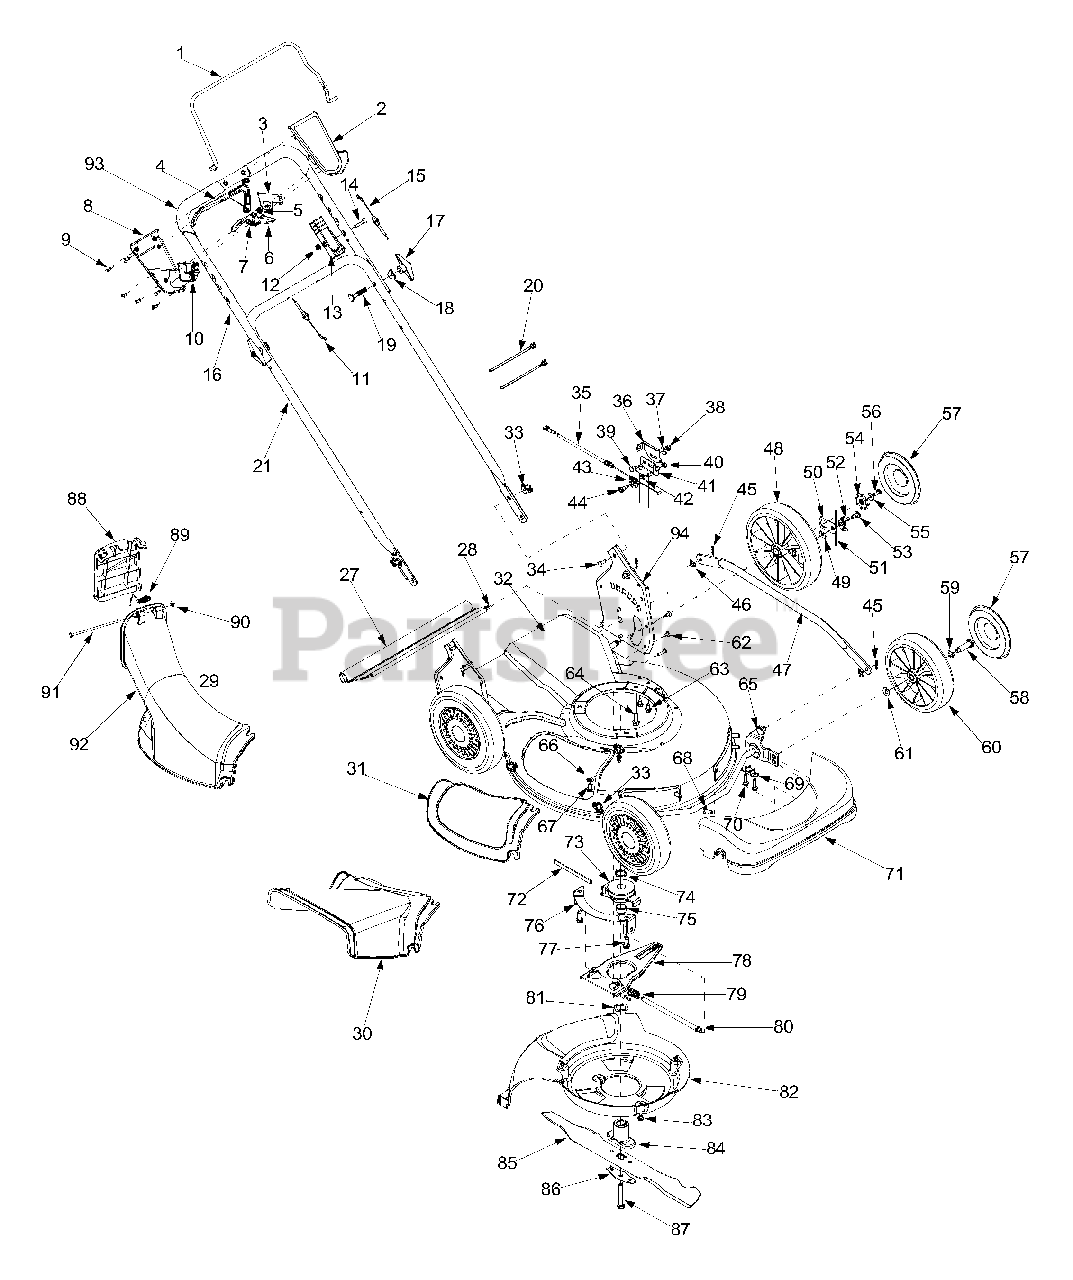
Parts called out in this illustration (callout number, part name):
1	Control Handle
2	Control Housing Kit
3	6 Spd. Rack Cable Bracket
4	Control Lever
5	Gear Insert
6	Shift Lever Spring
7	6 Speed Shift Lever
8	Control Housing Kit
9	C Sunk Tap Screw #10 x .75 Lg
10	Control Housing Kit
11	Drive Cable 51.0
12	Top Lock Nut 1/4-20
13	Control Housing
14	Oval C-Sunk Screw
15	Control Cable 46"
16	Upper Handle
17	Wing Nut
18	Saddle Washer .320 ID x .830 OD
19	Carriage Bolt 5/16-18 x 2.0
20	Cable Tie
27	Trail Shield
28	Trail Shield Wire
29	Chute Assembly
30	Side Discharge Chute
31	Mulch Cover
34	Carriage Bolt 1/4-20 x .75
35	6 Speed Cable
36	Cable Adjustment Bracket
37	Bell Washer .265 ID x .75 OD
38	Hex Nut 1/4-20
39	Carriage Screw 1/4-20 x .50
40	Hex Nut 1/4-28
41	Cable Mounting Bracket
42	Lock Washer 1/4
43	Roller Cable
44	Shoulder Screw .375 ID x 1/4-14
45	Cotter Pin
46	Bowed Washer
47	Single Lever Control Arm
48	Wheel 9 x 2
49	Top Lock Tab Weld Nut 1/4-20
50	Ratchet Pawl Plate
51	Plastic Spring Ratchet
53	Shld Screw .340 ID x .285 OD
54	Wheel Rachet
55	Bell Washer .265 ID x .75 OD
56	Hex Cap Screw 1/4-20 x .620
57	Hubcap
58	Shoulder Screw .498 x 1.445
59	Wave Washer .510 ID x .750 OD
60	Wheel 8 x 2
61	Spring Washer .401 ID x .870 OD
62	Screw 1/4-14 x .500
63	Screw 1/4-14 x .625
64	Hex Washer Screw 3/8-16 x 1.0
65	Front Axle Assembly
66	Flat Washer .344 ID x .62 OD
67	Carriage Screw 1/4-20 x .75
68	Torx Screw
69	Block Bushing
70	Hex Washer Screw
71	Front Axle Cover
72	Belt 3/8 x 39.24
73	Pulley Assembly
74	Sleeve Spacer .88 ID x 1.13 OD
75	Sleeve Spacer .88 ID x 1.00 OD
76	Pivot Bracket
77	Screw 3/8-18 x 1.0
78	Control Arm
79	Torsion Spring
80	Pivot Shaft
81	Wave Washer 1.38 ID x .88 OD
82	Baffle
83	Screw 1/4-20 x 3.75
84	Blade Adapter Kit
85	21" Mulching Blade
86	Blade Bell Support
87	Hex Bolt 3/8-24 x 2.5
88	Chute Door
89	Torsion Spring
91	Pivot Rod
92	Discharge Chute
93	Grip
94	Handle Bracket Assembly - RH
